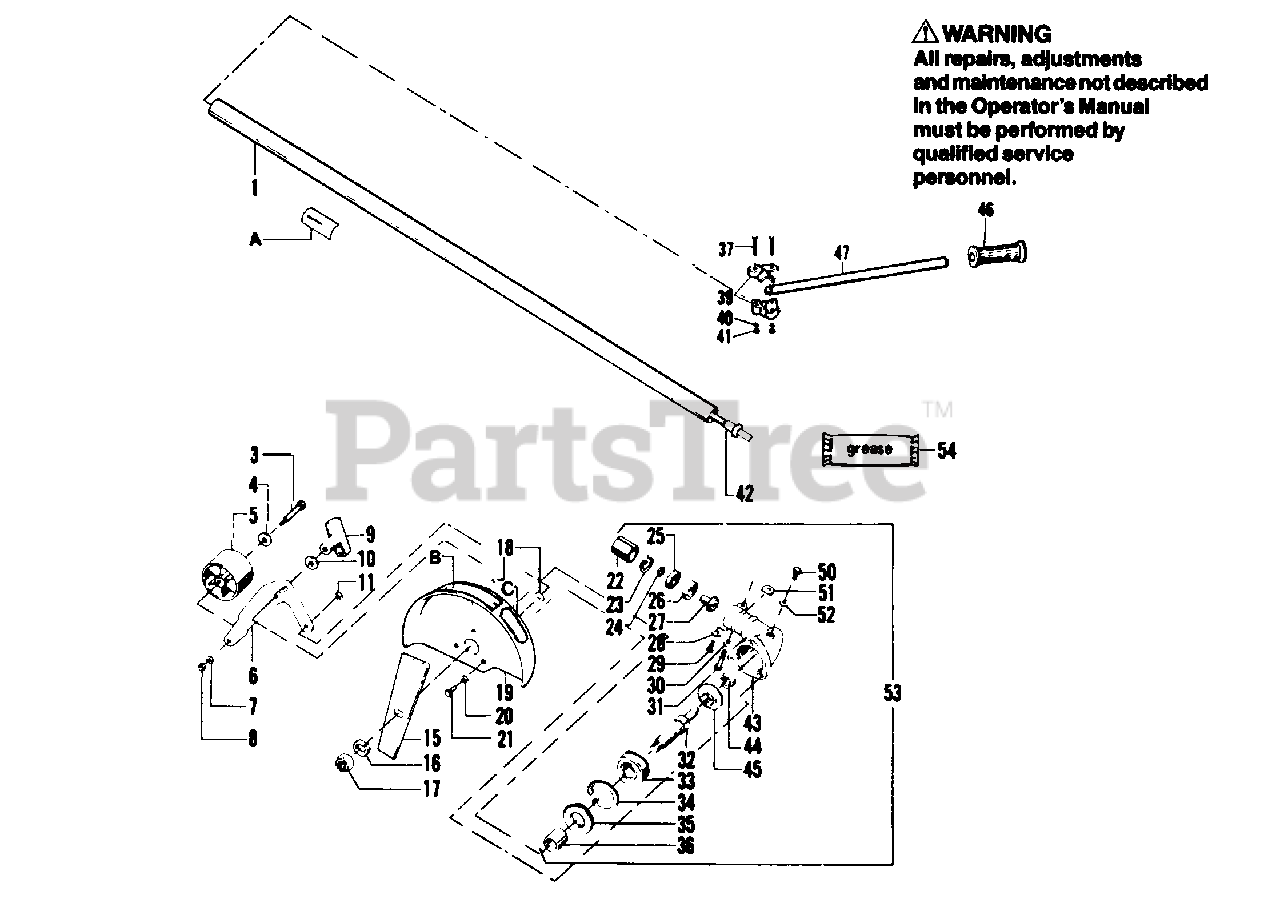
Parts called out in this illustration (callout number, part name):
1	Drive Shaft Housing Assembly
3	Shoulder-Bolt-Wheel #5/16-18 x 5/64"
4	Washer - #5/16-Wheel
5	Wheel - Depth Adjusting
6	Bracket - Wheel
7	Lockwasher - #5/16 - Wheel to Bracket
8	Nut-Bracket to Guard - #5/16 - 18-Hex
9	Knob - Wheel
10	Washer - #1/4 -Knob
11	Locknut-Bracket to Guard - #1/4-20
16	Lockwasher - #7/16 - Blade Mounting
17	Nut - #7/16 - 14 - Blade Mounting
18	Washer - #1/4 - Bracket to Guard
19	Guard Assembly
20	Lockwasher - #1/4 - Guard to Gear Housing
21	Screw - Guard to Gear Housing - #1/4-20 x 1/2"
22	Sleeve - Drive Shaft Tube
23	Retaining Ring
24	Retaining Ring - Pinion
25	Bearing - Sealed
26	Bearing - Open
27	Gear - Pinion
28	Lockwasher - #10 - Index Screw
29	Screw - Index - #10-24 x 1/2"
30	Lockwasher 1/4 - Pinch Clamp
31	Screw - Pinch Clamp - #1/4-20 x 1-3/16"
32	Shaft - Output
33	Bearing - Large
34	Retaining Ring
35	Seal - Oil
36	Collar - Shaft
37	Bolt - Bracket #1/4-20 x 1 - 1/4"
39	Bracket - Handlebar
40	Lockwasher - #1/4 - Bracket
41	Nut - Bracket - #1/4-20 - Hex
42	Drive Shaft Assembly
43	Gear Housing
44	Bearing - Small
46	Grip - Handlebar
47	Handlebar
50	Screw - Lubrication Filler - #5/16-18 x 3/8
51	Spacer 5/16 - Fiber - Pinch Clamp
52	Washer - Fiber
53	Gear Housing Assembly (Inc. #'s 22-36, 43-45 & 50-52)
54	Drive Shaft Lube
A	Decal - Handlebar Location
B	Decal - Guard
C	Decal - Blade Rotation
